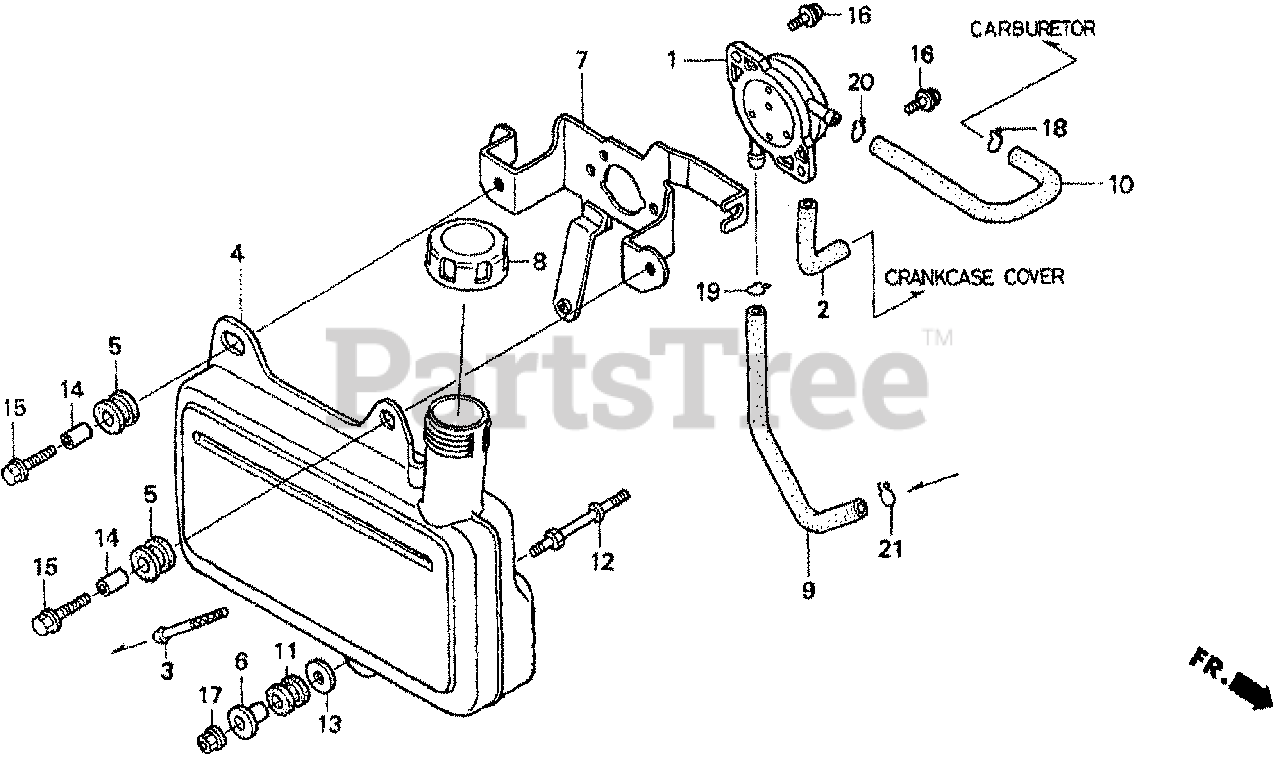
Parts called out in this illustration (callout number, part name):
1	PUMP ASSY., FUEL
2	TUBE, DIAPHRAGM
3	FILTER, FUEL
4	TANK, FUEL
5	RUBBER B, TANK MOUNTING
6	COLLAR, FUEL TANK SETTING
7	STAY A, FUEL TANK
8	CAP ASSY., FUEL TANK
9	TUBE, FUEL TANK
10	TUBE, FUEL
11	RUBBER, RR. FENDER
12	BOLT, STUD (F/TANK)
13	WASHER (8MM)
14	COLLAR (14X6.1)
15	BOLT-WASHER (6X25)
16	SCREW-WASHER (5X14)
17	NUT, FLANGE (6MM)
18	CLIP, TUBE (B8)
19	CLIP, TUBE (B10)
20	CLIP, TUBE (C9)
21	CLIP, TUBE (C11)
